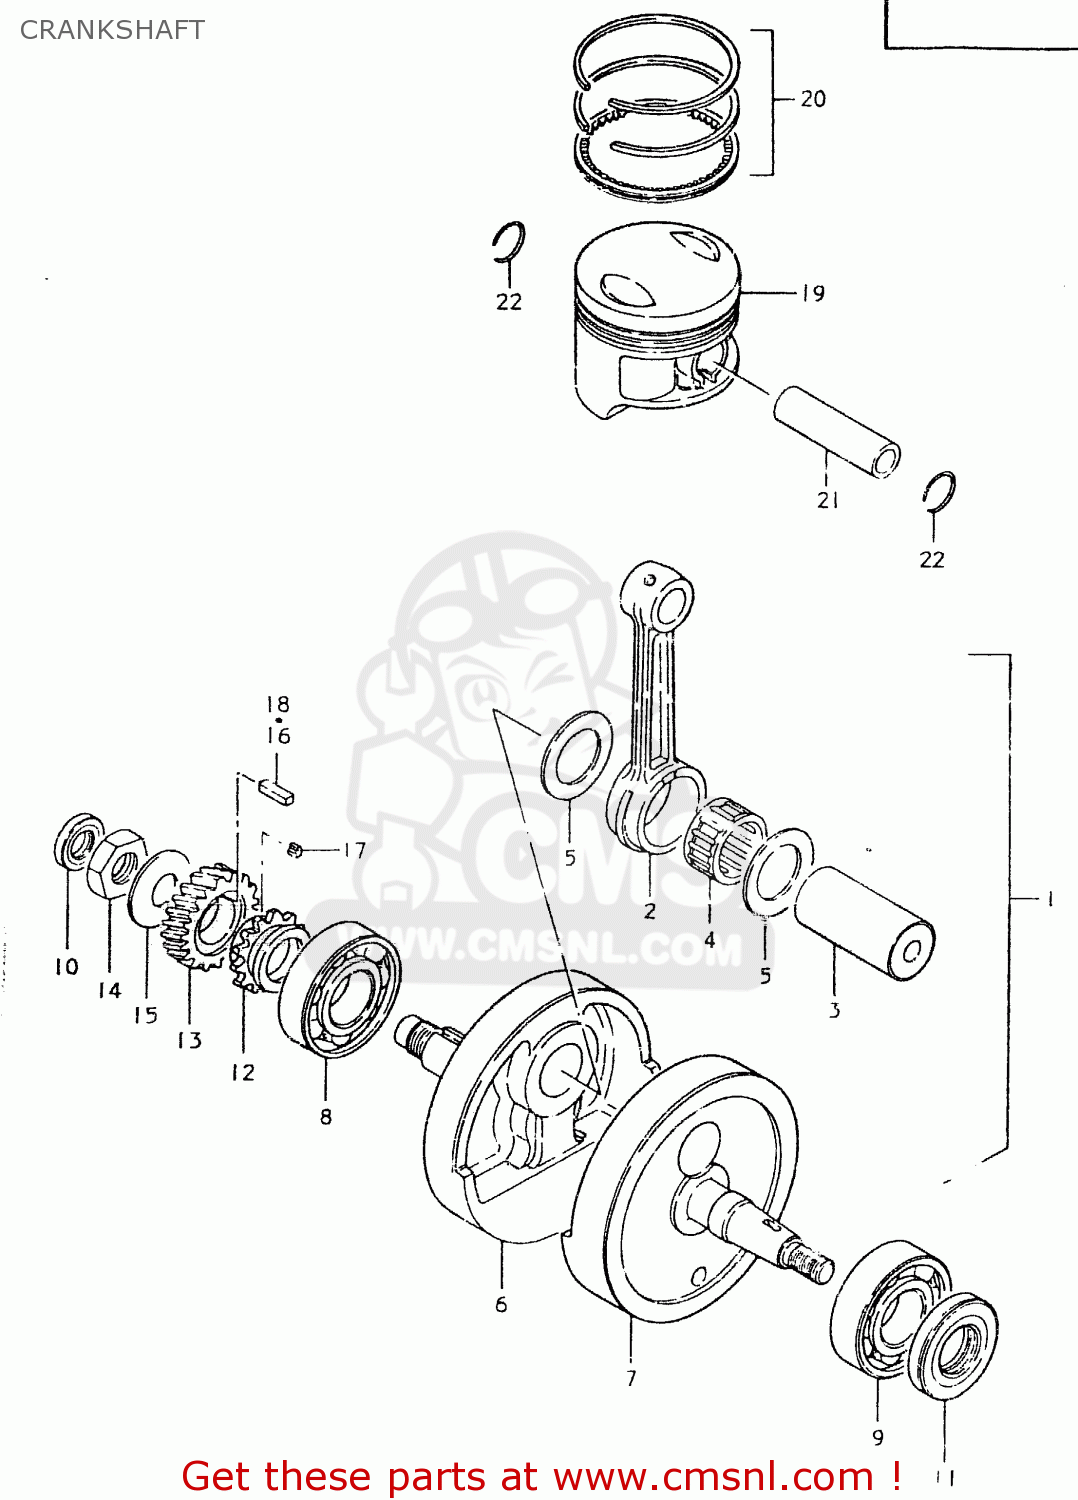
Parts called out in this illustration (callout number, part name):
1	CRANKSHAFT ASSEMBLY
2	ROD,CONNECTING
3	PIN,CRANK
4	BEARING
5	WASHER(34X52X1)
6	CRANKSHAFT
7	CRANKSHAFT,LEFT
8	BALL BEARING 30X72X19
9	BALL BEARING 30X72X19
10	SEAL,OIL(16X30X6)
11	SEAL,OIL(30X58X7)
12	SPROCKET,CAM CHAIN DRIVE
13	GEAR,PRIMARY DRIVE
14	NUT (20MM)
15	WASHER
16	KEY
17	KEY,SPROCKET
18	KEY
19	PISTON
20	RING SET,PISTON
21	PIN,PISTON
22	CIRCLIP
